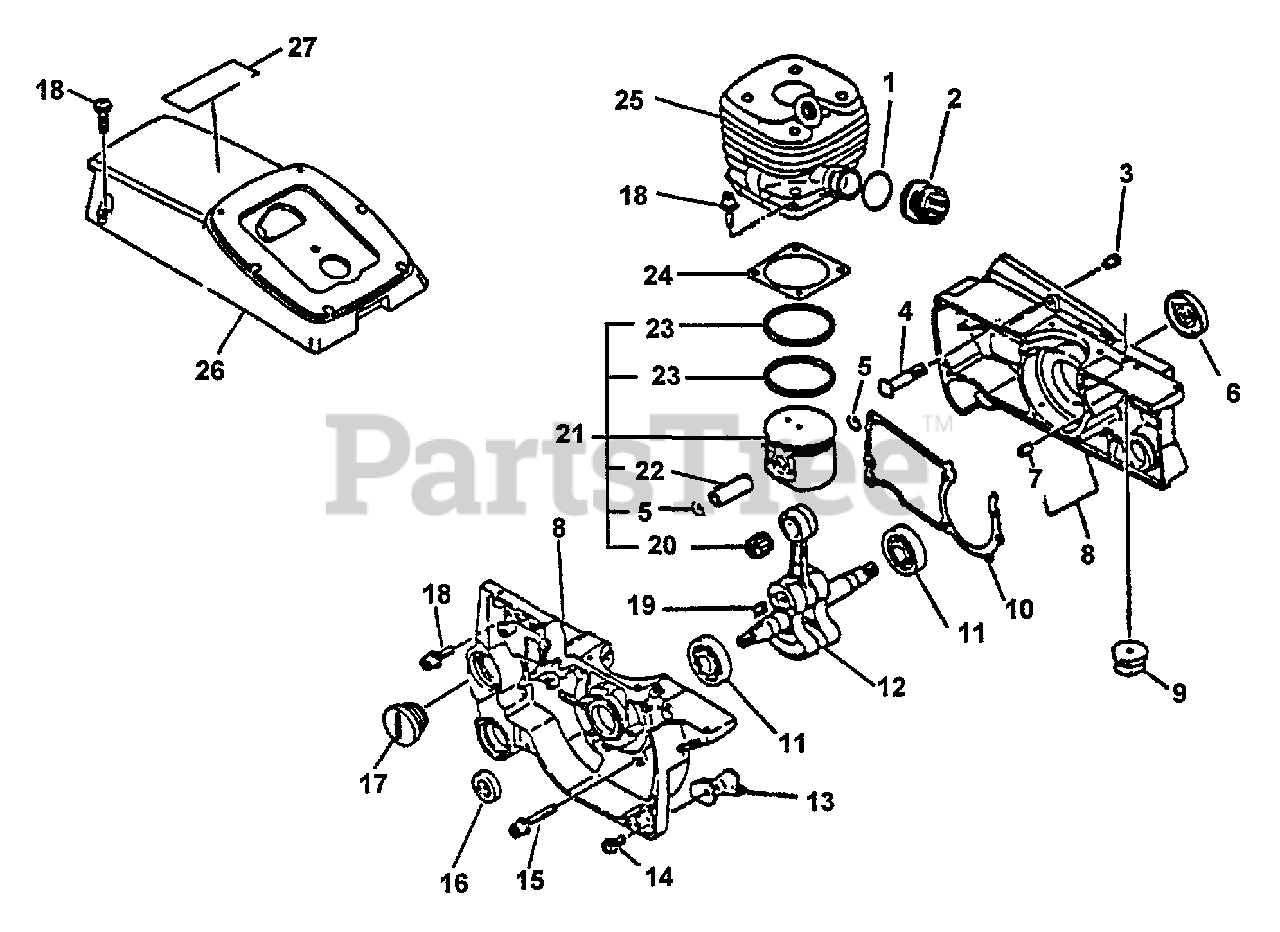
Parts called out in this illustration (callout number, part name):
2	ADAPTOR, INTAKE
3	VENT ASSY
5	RING, SNAP
6	SEAL, OIL
7	PIN, LOCATING 5×10
8	CRANKCASE KIT
10	GASKET, CRANKCASE
11	BEARING, BALL 6202
12	CRANKSHAFT ASSY
14	SCREW 5×14
15	BOLT M5×35
16	SEAL, OIL
17	PLUG
18	BOLT 5×20
19	KEY, WOODRUFF
20	BEARING, NEEDLE
21	PISTON KIT
22	PIN, PISTON
23	RING, PISTON
24	GASKET, CYLINDER
25	CYLINDER KIT
26	COVER, ENGINE
27	LABEL, CAUTION
